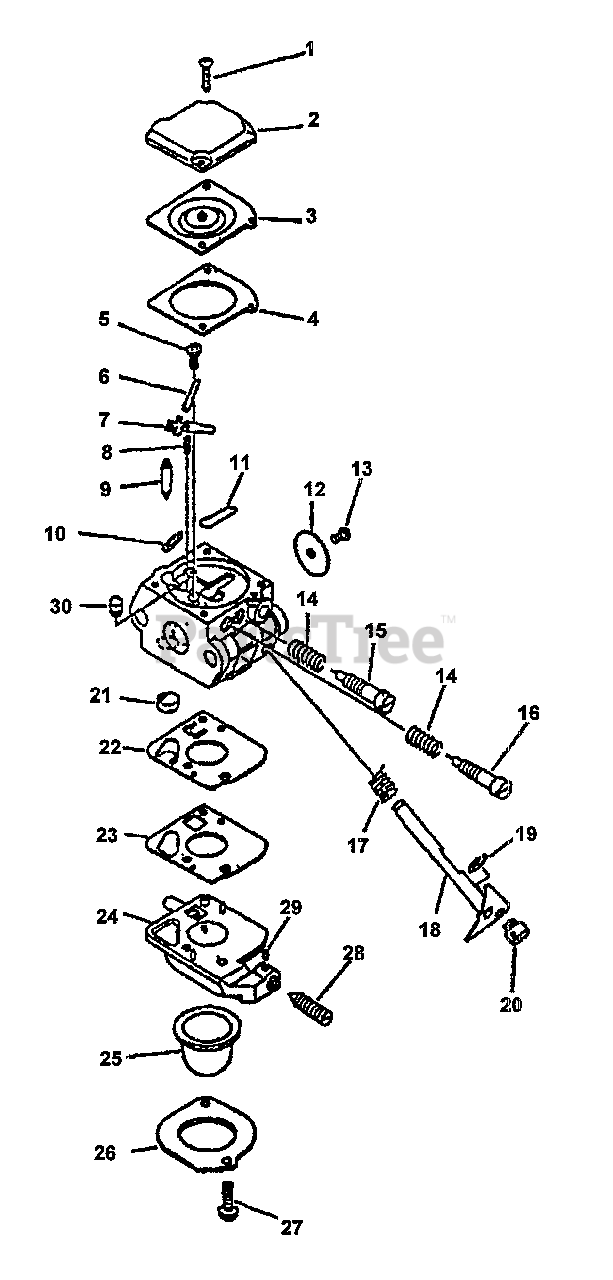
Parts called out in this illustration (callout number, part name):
2	COVER, DIAPHRAGM
3	DIAPHRAGM
4	GASKET, METERING
6	PIN, METERING LEVER
7	LEVER, METERING
8	SPRING
9	VALVE, INLET NEEDLE
11	PLUG, WELCH
12	VALVE, THROTTLE
14	SPRING, NEEDLE
15	NEEDLE, IDLE
16	NEEDLE, HIGH SPEED
17	SPRING, THROTTLE RETURN
18	SHAFT, THROTTLE
21	STRAINER
24	BODY ASSY, PURGE
25	BULB, PURGE
26	RETAINER
28	SCREW, IDLE ADJUST
29	PIECE, FRICTION
30	NOZZLE, CHECK VALVE
